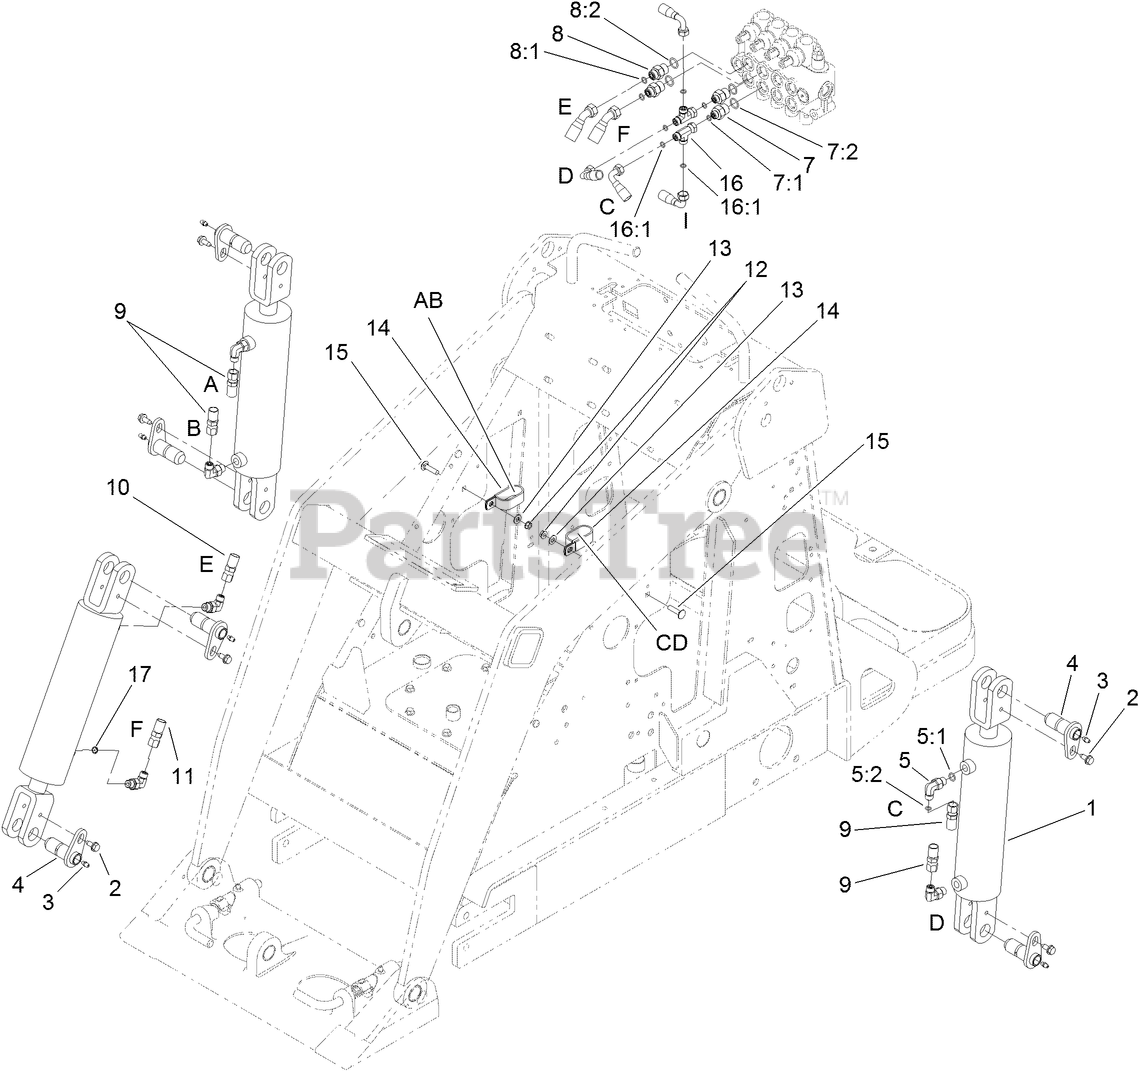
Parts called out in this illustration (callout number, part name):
1	CYLINDER-HYD
2	BOLT-SHOULDER
3	FITTING-GREASE
4	PIN-PIVOT
5	FITTING-ELBOW 90
5:1	O-RING
5:2	O-RING
7	FITTING-STR
7:1	O-RING
7:2	O-RING
8	FITTING-STRAIGHT
8:1	O-RING
8:2	O-RING
9	HOSE-HYD
10	HOSE-HYD
11	HOSE-HYD
12	NUT-LOCK, NI
13	WASHER-PLAIN
14	CLAMP-R, DOUBLE
15	SCREW-CARR
16	FITTING-HYD
16:1	O-Ring
17	ORIFICE-PORT INSERT, ONE WAY
